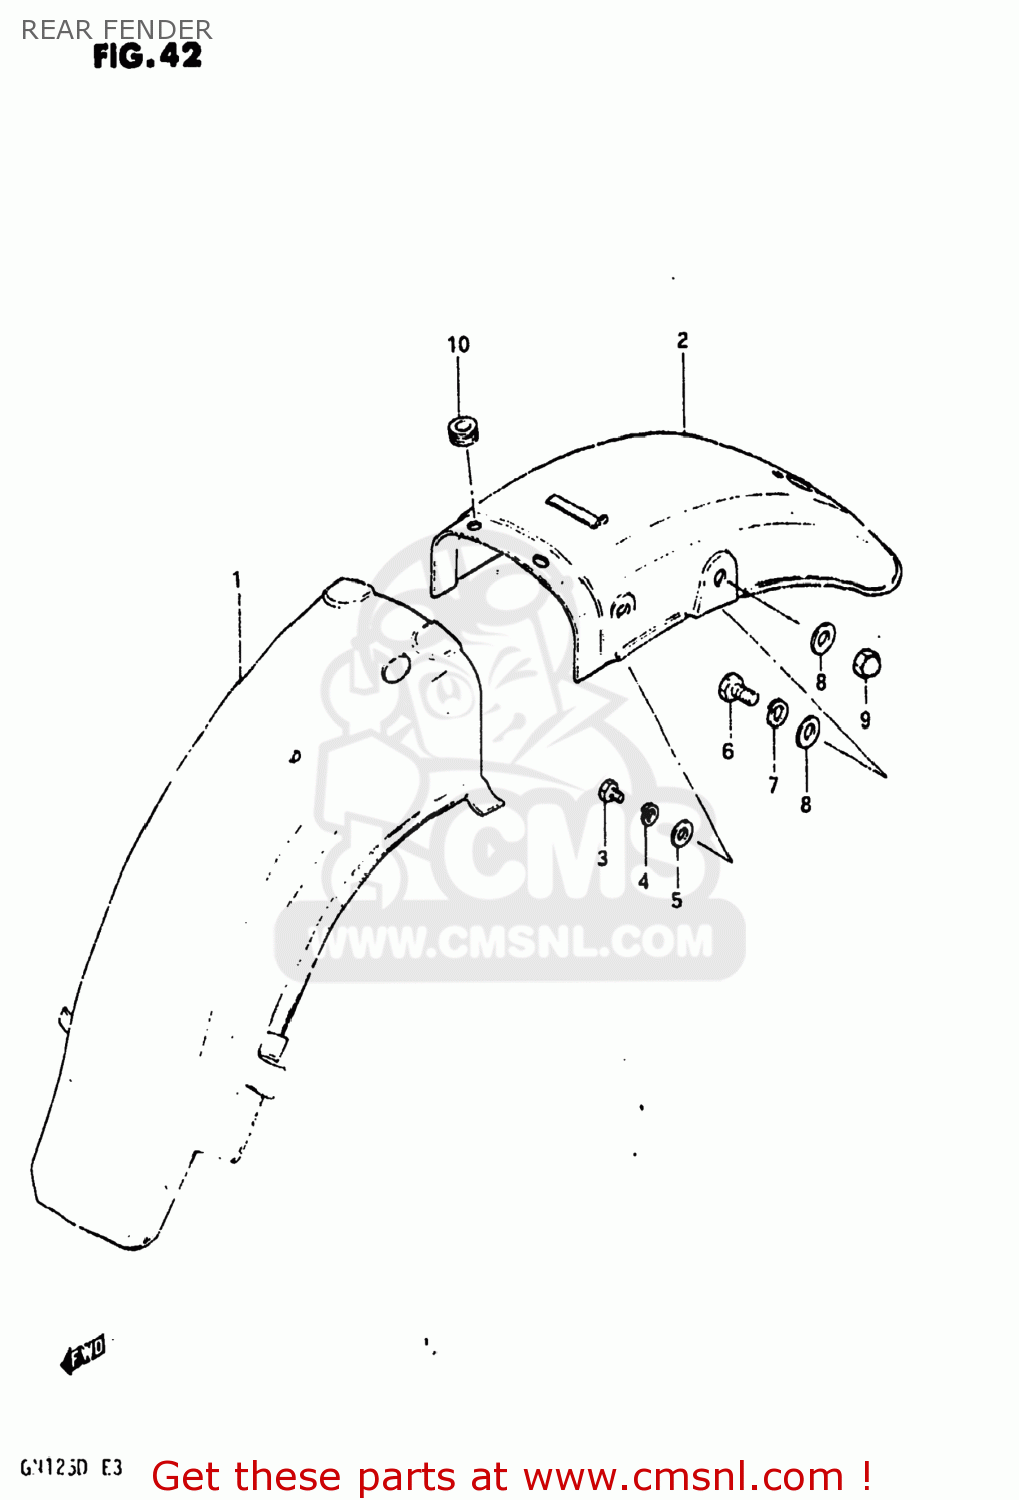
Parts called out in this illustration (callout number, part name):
1	FENDER,REAR
2	FENDER,REAR
3	BOLT
4	LOCK WASHER
5	WASHER
6	BOLT
7	LOCK WASHER
8	WASHER
9	NUT
10	CUSHION
